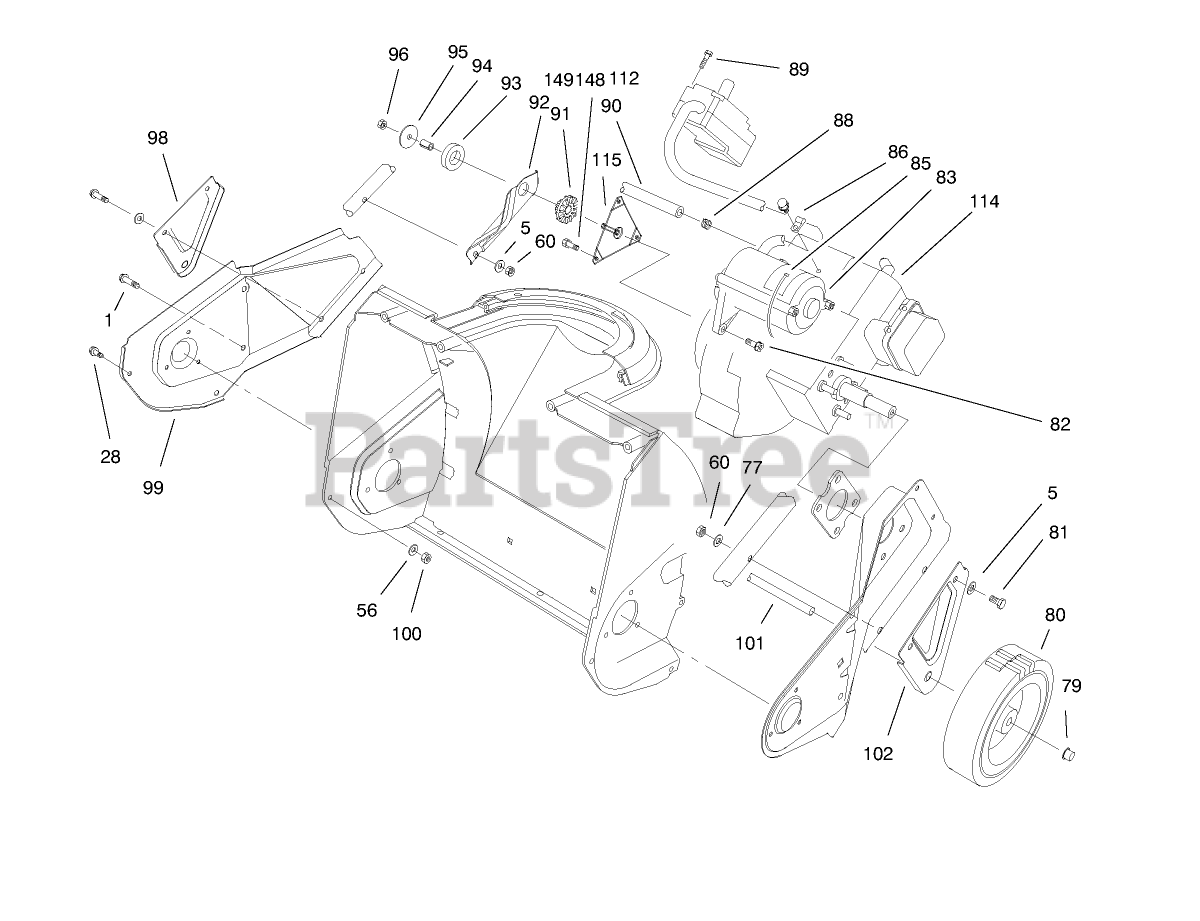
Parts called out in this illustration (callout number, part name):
1	SCREW-PLASTIC
5	WASHER-FLAT
56	WASHER-FLAT
60	NUT-LOCK, NI
77	WASHER
79	RETAINER-PUSH ON
80	WHEEL
81	SCREW-HH
82	SCREW-HH, TORX
83	ASM-Switch Housing
85	TIE-CABLE
86	CLAMP
88	CLAMP-HOSE
89	SCREW-PLASTITE
90	LINE-GAS
91	BUSHING-ISOLATOR
92	Support-Engine
93	RING-ISOLATOR
94	SPACER-TUBULAR
95	WASHER-FLAT
96	NUT-LOCK, NI
98	Bracket-Wheel
99	Sideplate-RH
100	NUT-LOCK, NI
102	Bracket-Wheel
112	SCREW
115	BRACKET AND STUD ASM
148	SCREW
149	WASHER-LOCK / EXT
